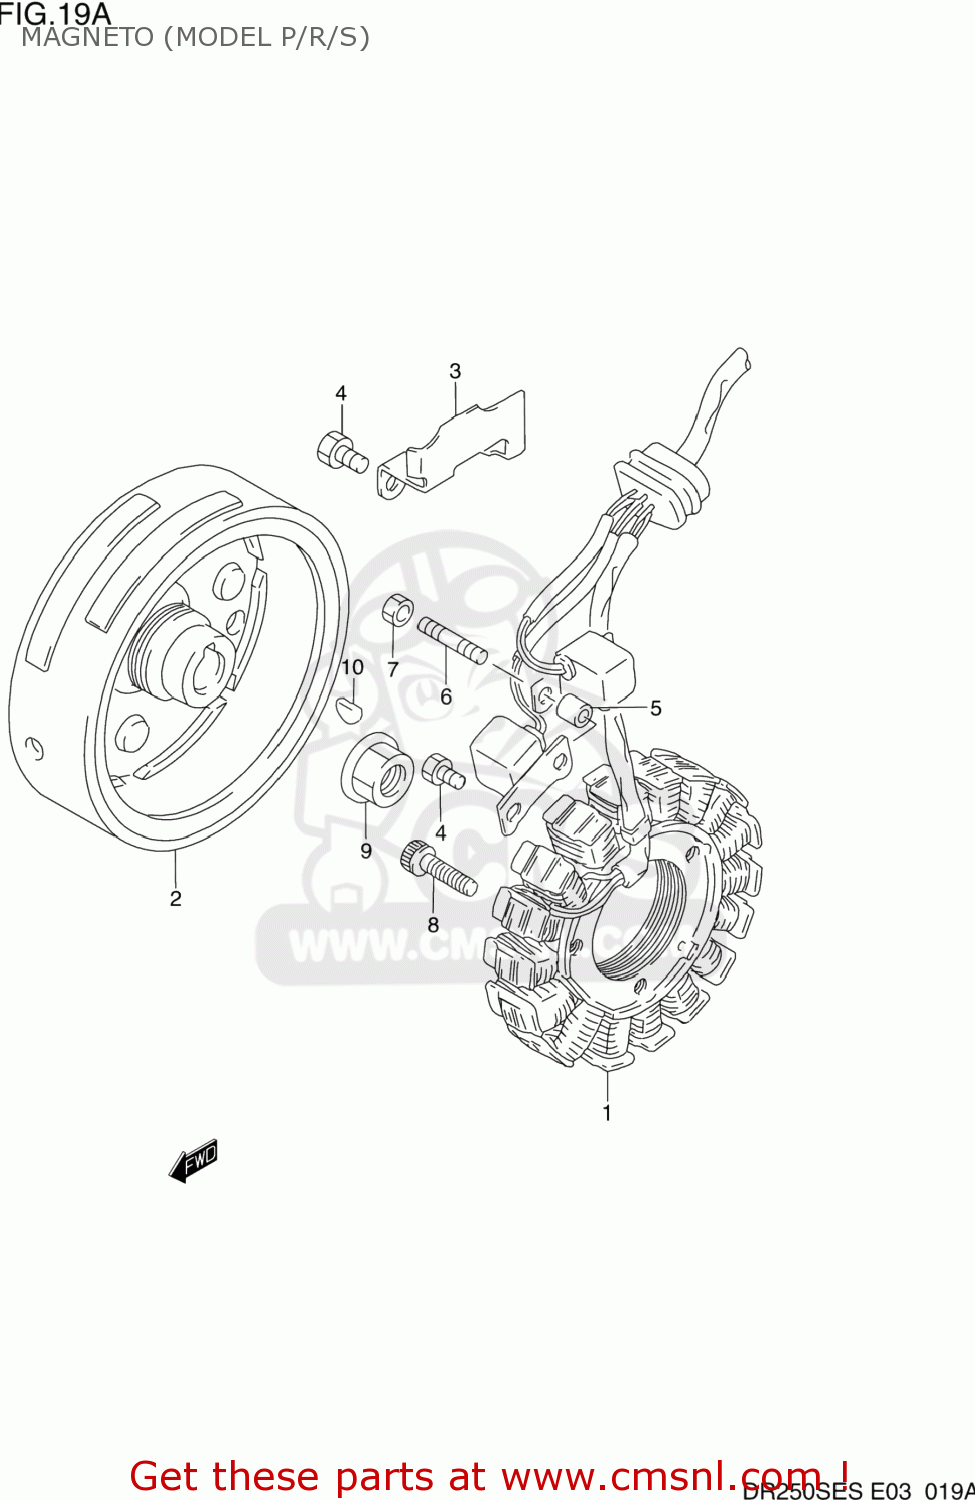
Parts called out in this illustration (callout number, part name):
1	STARTER ASSY
2	ROTOR
3	CLAMP,MAGNETO LEAD WIRE
4	BOLT(5X10)
5	SPACER (5.5X9.5X6.5)
6	BOLT,STUD(5X18)
7	NUT
8	BOLT
9	NUT
10	KEY
